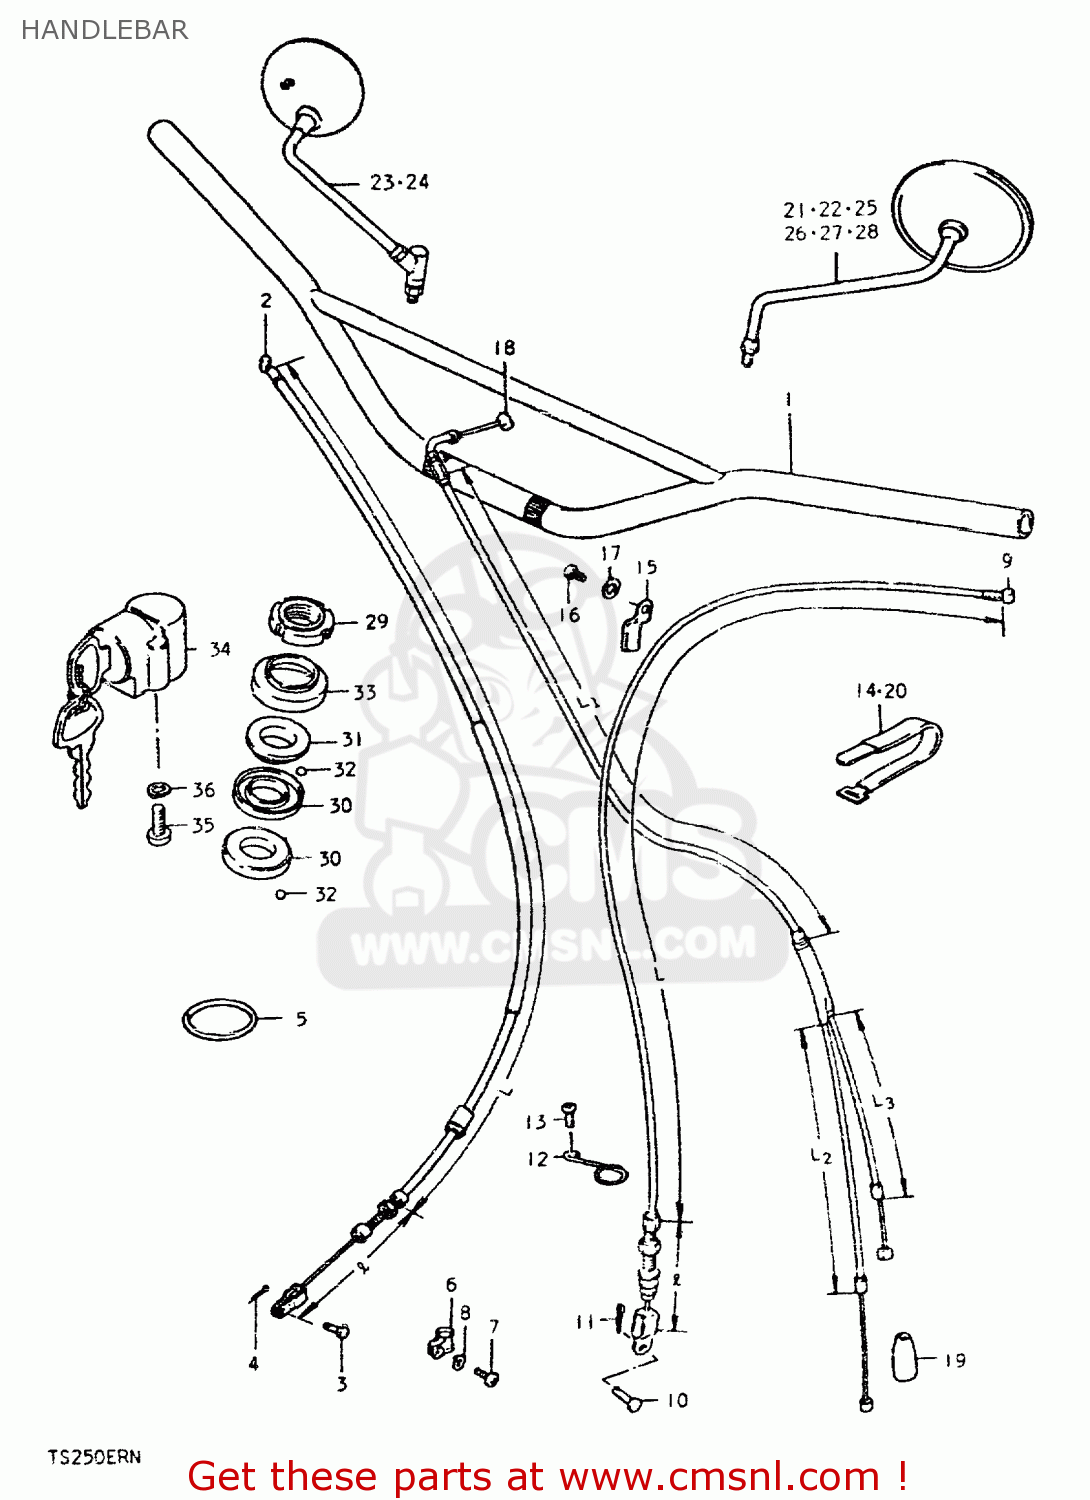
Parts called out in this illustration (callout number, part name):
1	HANDLEBAR
2	CABLE ASSEMBLY,FRONT BRAKE
3	PIN(L:17.5)
4	PIN
5	O RING(D:3.53,ID:69.44)
6	GUIDE,CABLE
7	SCREW
8	LOCK WASHER
9	CABLE ASSY,CLUTCH
10	PIN(L:15)
11	PIN
12	CLIP
13	SCREW
14	CLAMP
15	CLAMP
16	SCREW 6X12
17	WASHER
18	CABLE ASSEMBLY,THROTTLE
19	SEAL,DUST(7X18X30)
20	CLAMP
21	MIRROR ASSEMBLY,RIGHT
22	MIRROR ASSEMBLY,LEFT
23	MIRROR ASSY,RH
29	NUT,STEERING STEM(25X44X10)
30	LACE,STEERING INNER LWR
31	LACE,STEERING OUTER UPR
32	BALL
33	DUST SEAL,STEERING UPR
34	LOCK ASSEMBLY,STEERING
35	SCREW
36	LOCK WASHER
